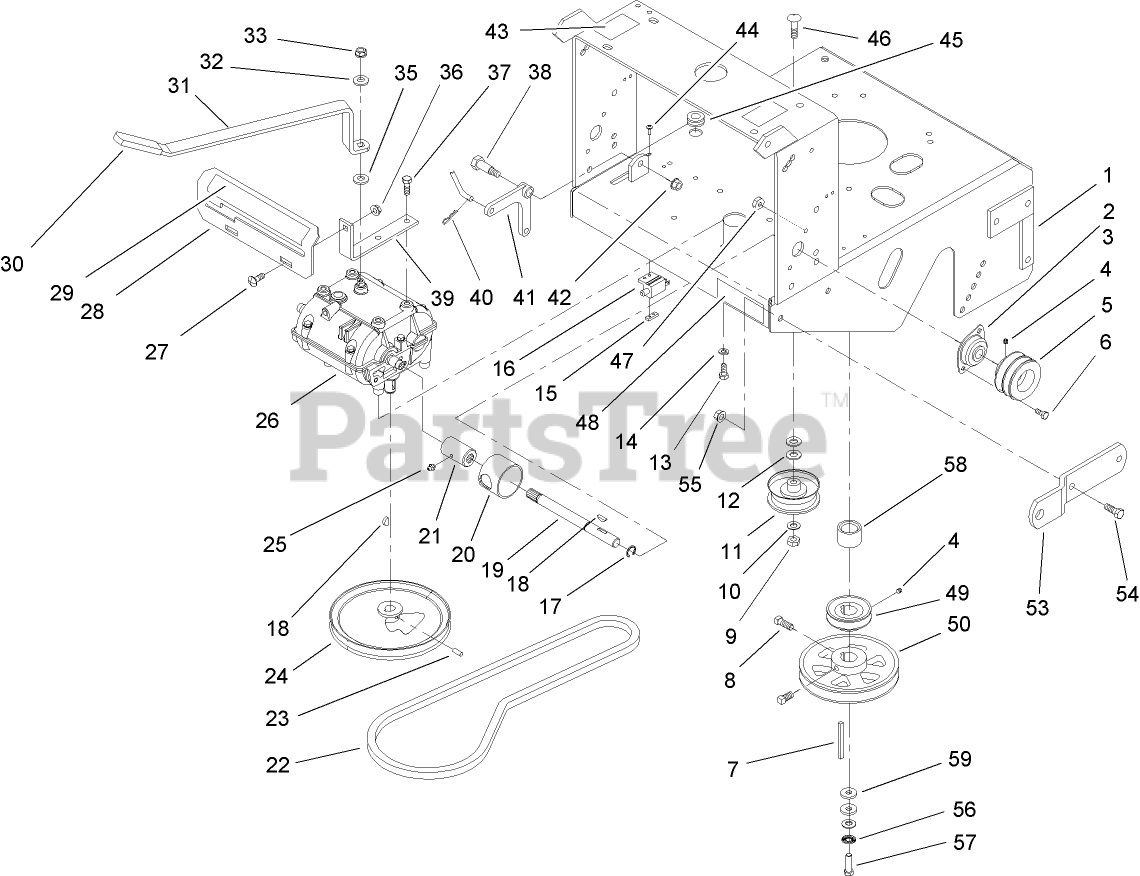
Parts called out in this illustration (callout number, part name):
1	FRAME-DECK, REAR
2	BEARING-SHAFT
3	FLANGE-OUTPUT
4	SCREW-SET
5	SHEAVE-TRANSMISSION
6	SCREW-HH
8	SCREW-SET, SQH
9	NUT-LOCK, NI
10	WASHER-FLAT
11	PULLEY-IDLER, FLAT
12	WASHER-FLAT
13	SCREW-HH
14	WASHER-LOCK
15	PLATE-TAPPED
16	SWITCH-CLOSED, NORMALLY
17	RING-RETAINING
18	KEY-WOODRUFF
19	SHAFT-TRANSMISSION
20	GUARD-COUPLER
21	COUPLER
22	V-BELT
23	SCREW-HSH
24	SHEAVE-TRANSMISSION
25	FITTING-GREASE
26	TRANSMISSION
27	BOLT-CARR
28	PLATE-SHIFT
29	DECAL-SPEED, GROUND
30	GRIP-LEVER
31	LEVER-SHIFT
32	WASHER-BELLEVILLE
33	NUT-LOCK
35	WASHER
36	NUT-HF
37	SCREW-HWH, THREAD CUT
38	BOLT-SHOULDER
39	BRACKET-PLATE, SHIFT
40	PIN-COTTER
41	BELLCRANK
42	NUT-HHF, WHIZ
43	DECAL-SHUT OFF, FUEL
44	SCREW-PPH
45	GROMMET
46	SCREW-CARR
47	NUT-LOCK, NI
48	DECAL-CAUTION
49	Sheave-Transmission
50	SHEAVE
53	HITCH-SULKY
54	SCREW-HH
55	NUT-HHF, WHIZ
56	WASHER-SPRING
57	SCREW-HH
58	SPACER-CLUTCH
59	WASHER
